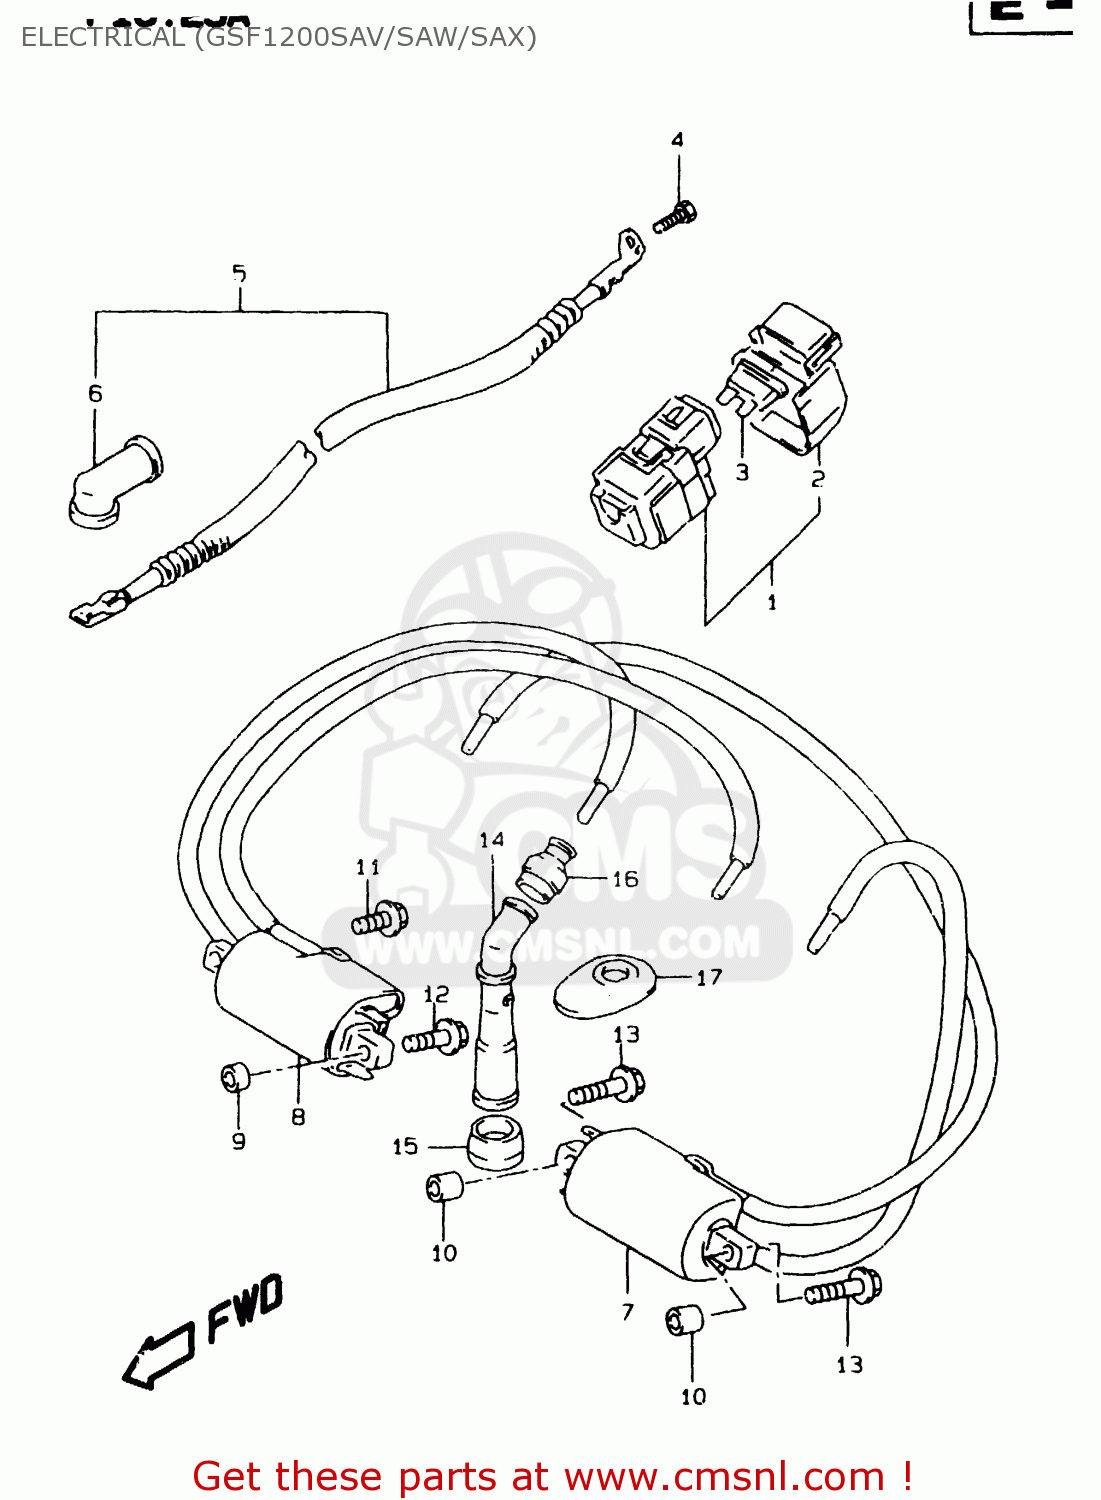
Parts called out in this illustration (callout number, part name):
1	RELAY ASSY,STARTING MOTOR
2	COVER,STARTER RELAY
3	FUSE(30A)
4	SCREW(6X8)
5	WIRE,STARTER MOTOR LEAD
6	CAP,STARTER MOTOR LEAD
7	COIL ASSY,IGNITION
8	COIL ASSEMBLY,IGNITION
9	SPACER(6X12X10)
10	SPACER(6.2X12X16)
11	BOLT
12	BOLT
13	BOLT
14	CAP,SPARK PLUG
15	SEAL,SPARK PLUG CAP
16	SEAL,HIGH TENSION CORD
17	COVER,SPARK PLUG CAP
